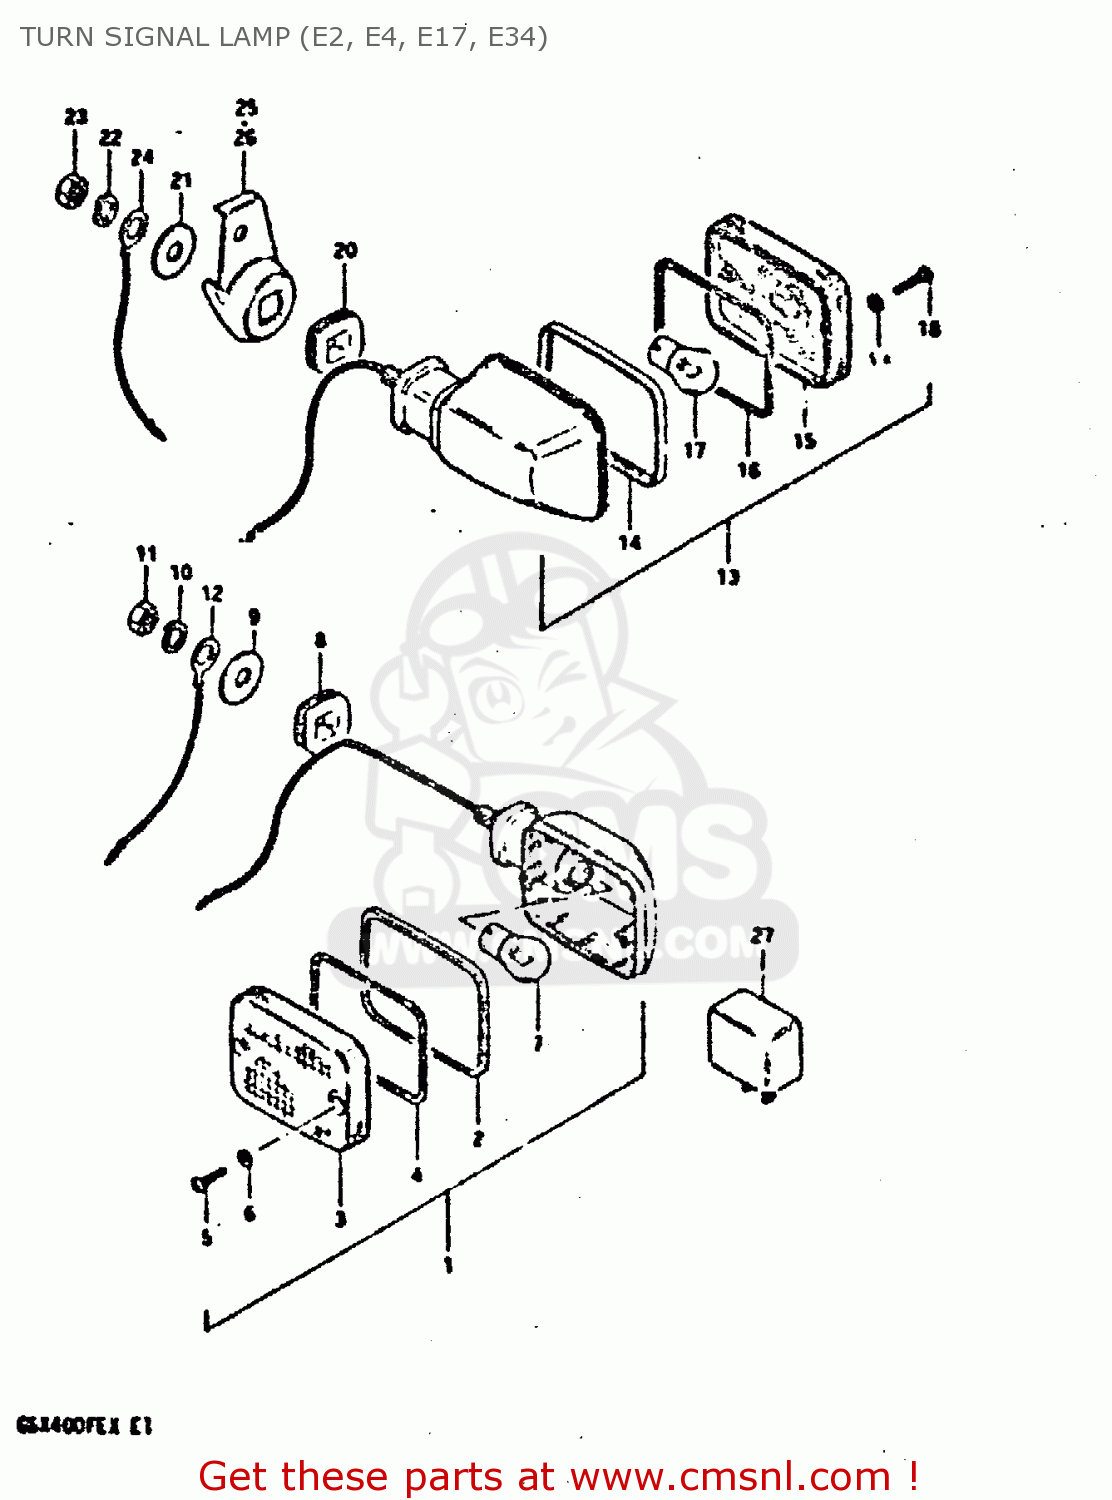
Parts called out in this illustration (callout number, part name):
1	LAMP ASSEMBLY,FRONT TURN SIGNAL
2	RIM
3	LENS
4	GASKET (NAS)
5	SCREW
6	GASKET (NAS)
7	BULB (12V, 21W)
8	CUSHION
9	WASHER (10.5X30X2.3)
10	LOCK WASHER
11	NUT
12	LEAD WIRE,EARTH
13	LAMP, REAR TURN SIGNAL
14	RIM
15	LENS
16	GASKET
17	BULB 12V 21W
18	SCREW
19	GASKET (NAS)
20	CUSHION
21	WASHER (10.5X30X2.3)
22	LOCK WASHER
23	NUT
24	LEAD WIRE,EARTH
25	BRACKET,REAR TURN SIGNAL
26	BRACKET,REAR TURN SIGNAL
27	RELAY,TURN SIGNAL
